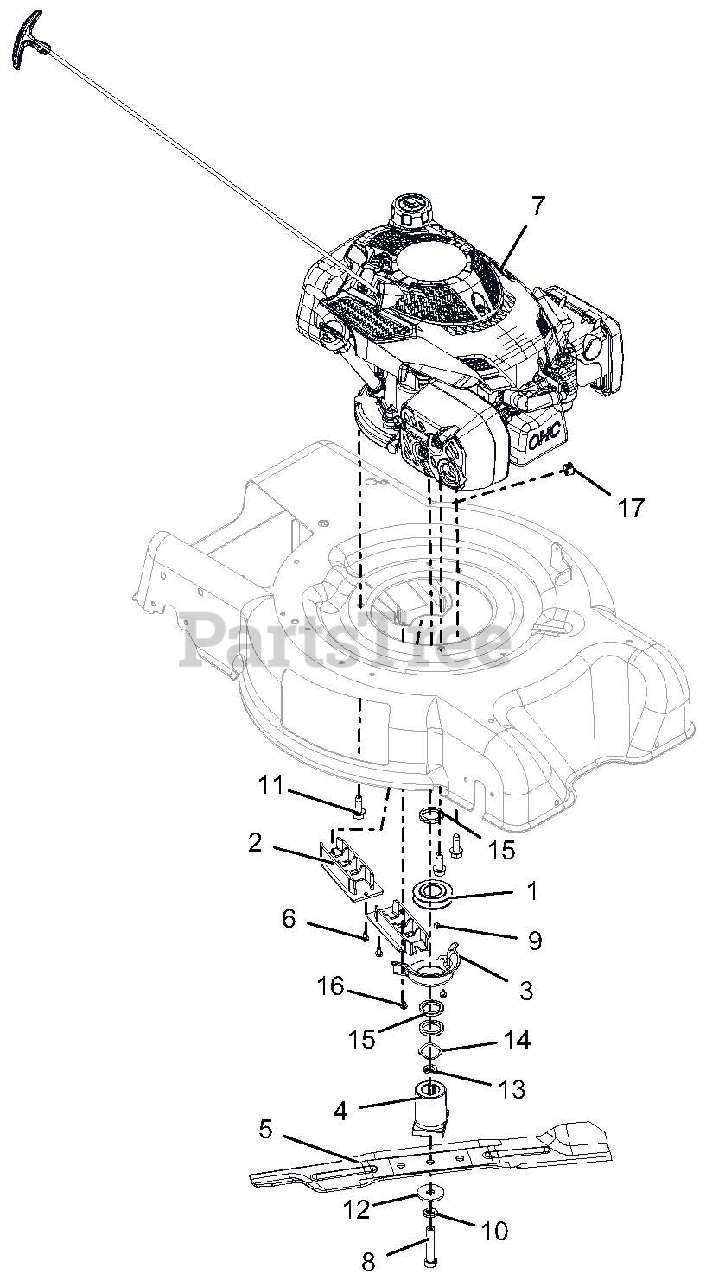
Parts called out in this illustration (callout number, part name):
1	PULLEY, MACHINED POWDER METAL
2	GUIDE, BELT INNER
3	GUIDE, BELT CRANKSHAFT
4	ADAPTOR, BLADE
5	BLADE, MOWER 21" HIGH-LIFT
6	SCR, TAP 10-24X.375 PRE-COAT 80
7	ENGINE, SUBARU 175CC VERT
8	BLT-HEX .44-20X2.25 GR8 YWZC
9	KEY-SQ .188X.188X.250
10	WSHR-LK .44X.109 REG YWZC
11	SCR-TAP .38-16X1.00 HWH TR YZ
12	WSHR-FL-STL .4375X1.50X.125 YWZC
13	WSHR-FL-STL .459X.750X.105 YWZC
14	WASHER, WAVE
15	SPCR, 1.00 X 1.375 X .179
16	SCR-TAP 10-24X.25 CRSLPH TR YZ
17	PLUG, DOME-BLACK, .625 DIA
